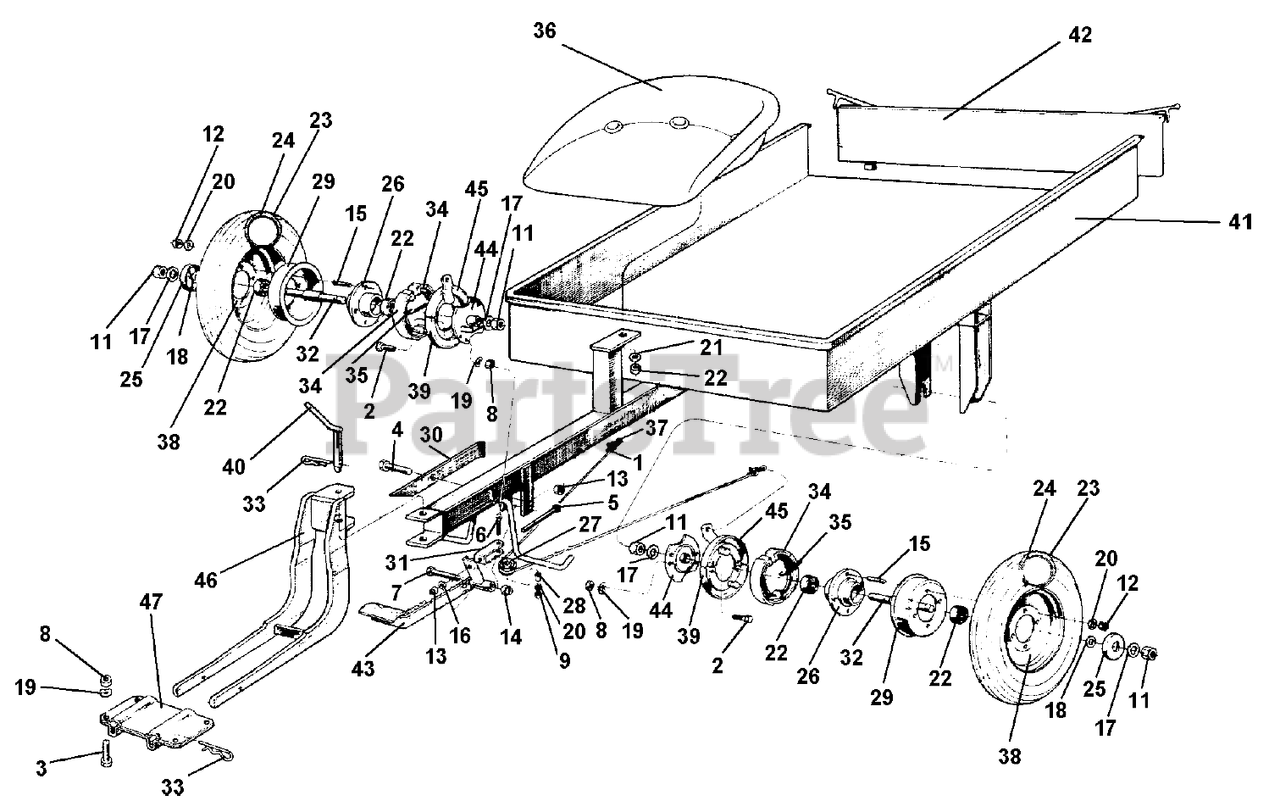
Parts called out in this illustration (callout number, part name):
1	CABLE CLAMP
2	SCREW M8 X 14
5	SCREW M8 X 115
6	SCREW M10 X 30
11	NUT M14 UNI 5588-5S
13	NUT, SELF LOCKING M8
14	NUT, SELF LOCKING M12
15	STUD M10 X 40 X 22 X 14
16	WASHER, FLAT 8.4
17	WASHER, FLAT 15
18	FLAT WASHER
19	WASHER, LOCK 8.4
20	WASHER, LOCK 10.5
21	WASHER, LOCK 13
22	BEARING 6202 Z 15 X 35 X 11
25	OUTSIDE HUB
27	BRAKE PULLEY
31	PULLEY FORK
32	WHEEL SHAFT
37	BRAKE CABLE
41	TRAILER BED
44	INSIDE RIGHT FLANGE
45	BRAKE DISC WITH SUPPORT
47	TOWBAR SUPPORT
